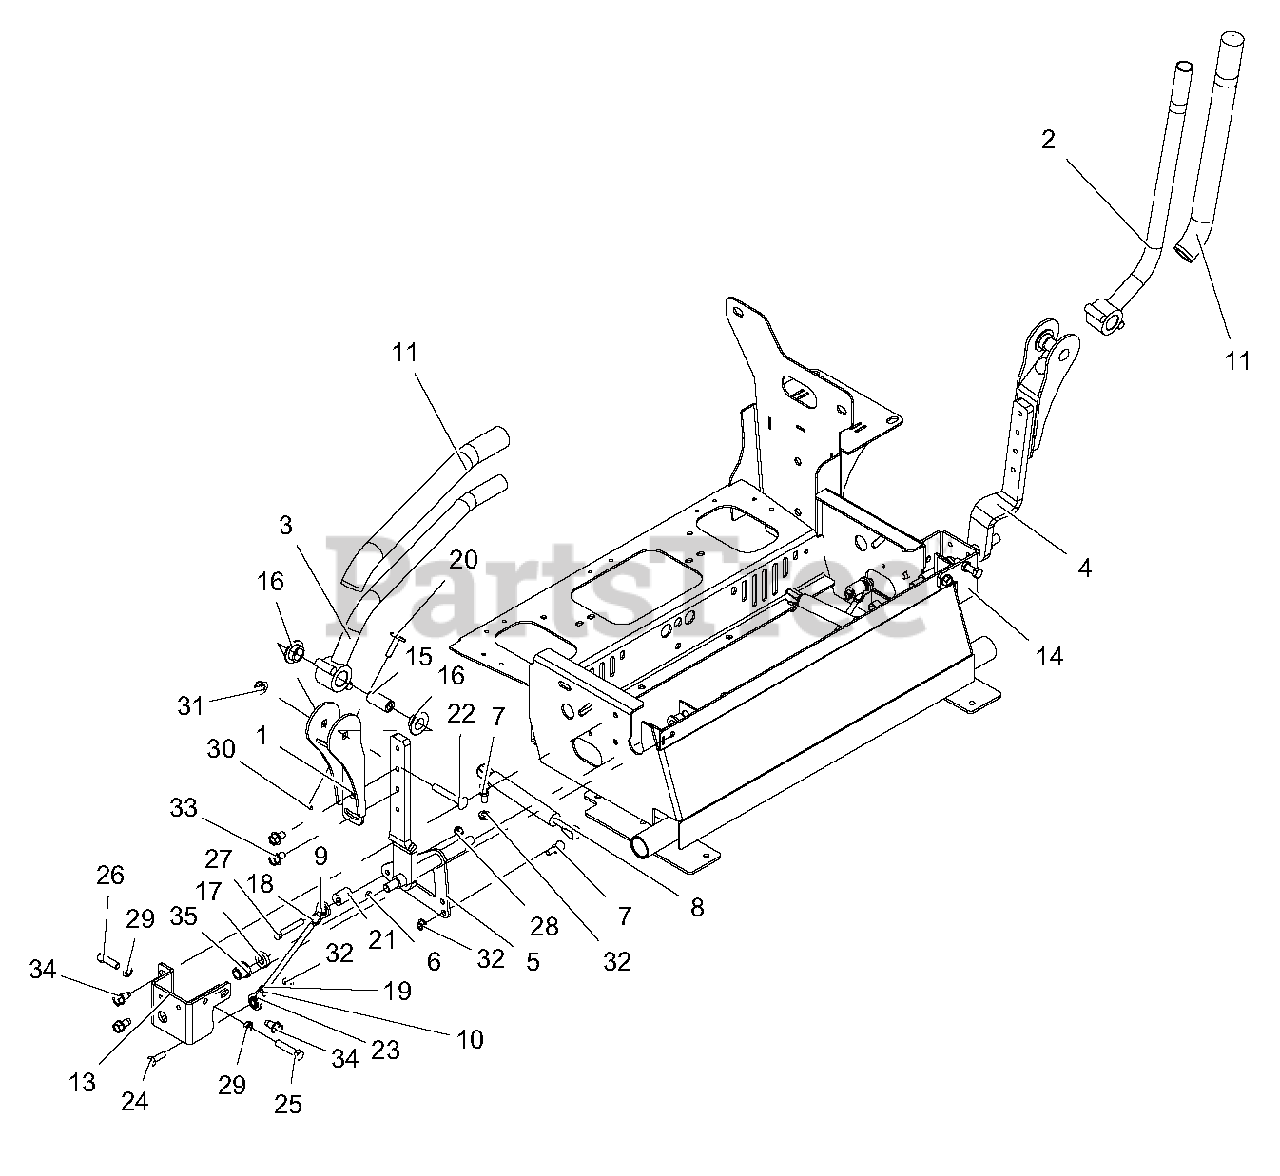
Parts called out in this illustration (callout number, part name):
1	MOUNT, STEERING ARM, ADJUSTABLE-BLACK
2	WLDMT, LH STEERING ARM
3	WLDMT, RH STEERING ARM
4	WLDMT, LH LOWER CONTROL ARM
5	WLDMT, RH LOWER CONTROL ARM
6	WAVE WASHER .531X.781X.125 FH
7	STUD-BALL
8	DAMPER,
9	ALIGNABALL, 5/16 RH THREAD
10	ROD, STEERING
11	GRIP, HANDLEBAR
13	BRKT, RH CONTROL ARM STOP-RED
14	BRKT, LH CONTROL ARM STOP-RED
15	SPCR, STEERING ARM
16	BSHG, FLANGE .762 X 1.48 X .44 NYLON
18	NUT-JAM
19	NUT, JAM -LH .31-24 YWZC
20	BUMPER, STUD MOUNTED
21	ECCENTRIC
22	@BLT-RHDSSQNK .38-16X2.50 G5YZ
23	ALIGNABALL, 5/16 LH THREAD
24	BLT-HEX .31-18X1.00 GR5 YWZC
25	BLT-HEX .38-16X1.75 GR5 YWZC
26	BLT-HEX .38-16X1.25 GR5 YWZC
27	BLT-HEX .31-18X2.00 GR5 YWZC
28	@NUT-LK-CTR .31-18 YWZC
29	NUT, JAM .375-16 YWZC
30	NUT, JAM .312-18 YWZC
31	NUT-LK-NYL-FLG .38-16 YWZC
32	@NUT, LK-TOP-FLG .312-18 YWZC
33	BLT-SERHFWH .38-16X.62 YWZC
34	SCR-TAP .38-16X.75 HWH TR YWZ
35	BHSG-FLG .500X.750X.750X.125
